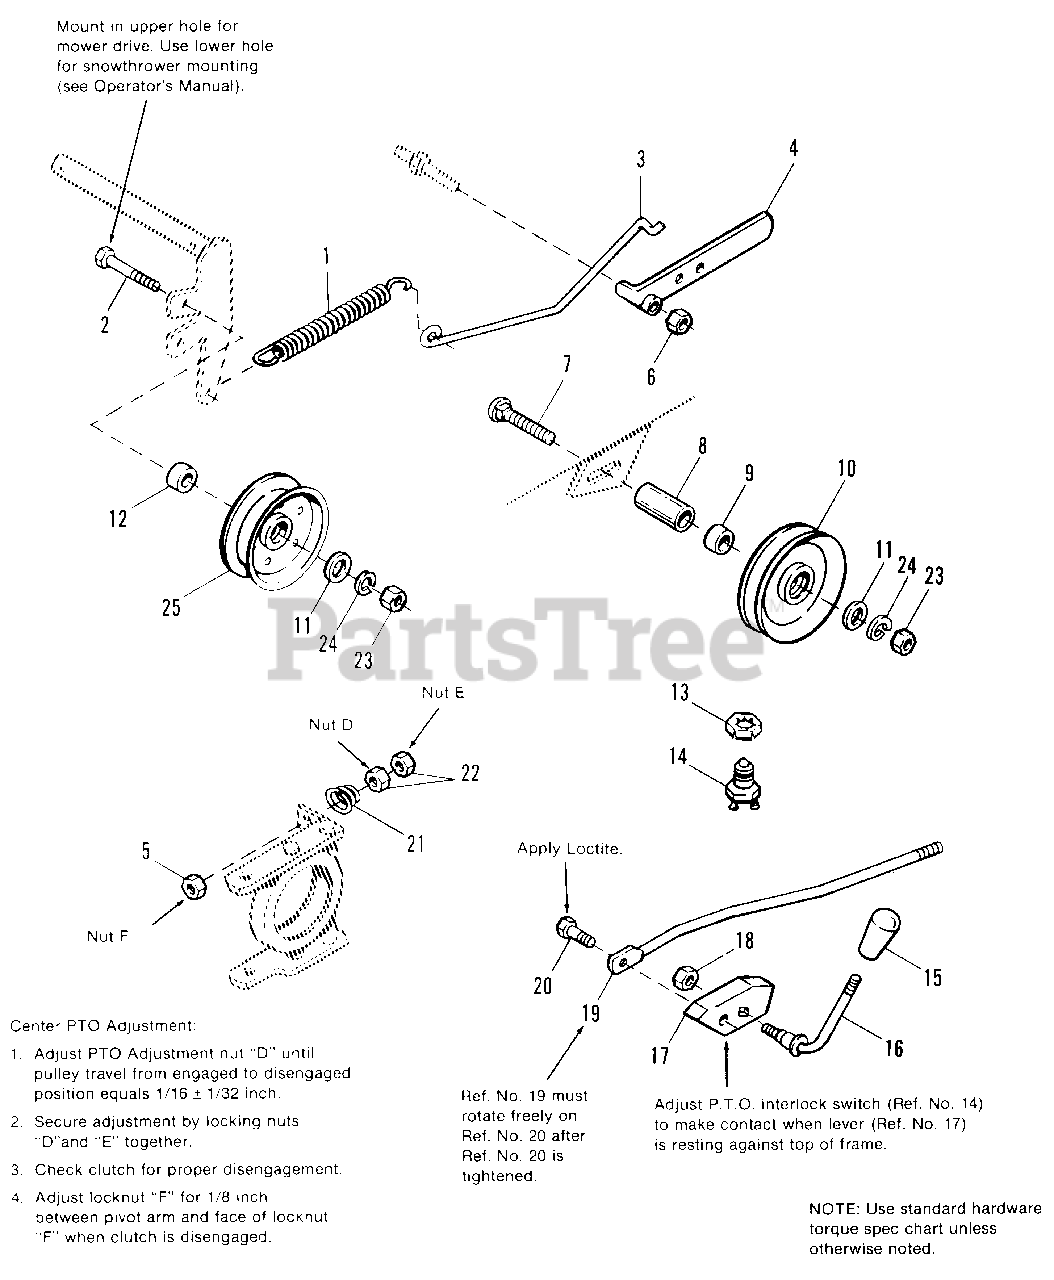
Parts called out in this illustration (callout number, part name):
1	SPRING, Tension
2	CAPSCREW, Hex HD., 3/8-16 x 2
3	ROD, Tension
4	HANDLE ASSY.
5	LOCKNUT, Hex, 5/16-18
6	LOCKNUT, Hex, 7/16-14
7	BOLT, Carriage, 3/8-16 x 1-3/4
10	PULLEY ASSY., w/ Bearings
11	WASHER, Plain, 3/8
14	SWITCH, Interlock
15	KNOB
16	HANDLE, PTO, Clutch
18	LOCKNUT, Hex, 3/8-16
19	ROD ASSY, Control
20	CAPSCREW, Special
22	NUT, Hex, Full, 5/16-18
23	NUT, Hex, Full, 3/8-16
24	LOCKWASHER, 3/8
25	PULLEY, Idler
